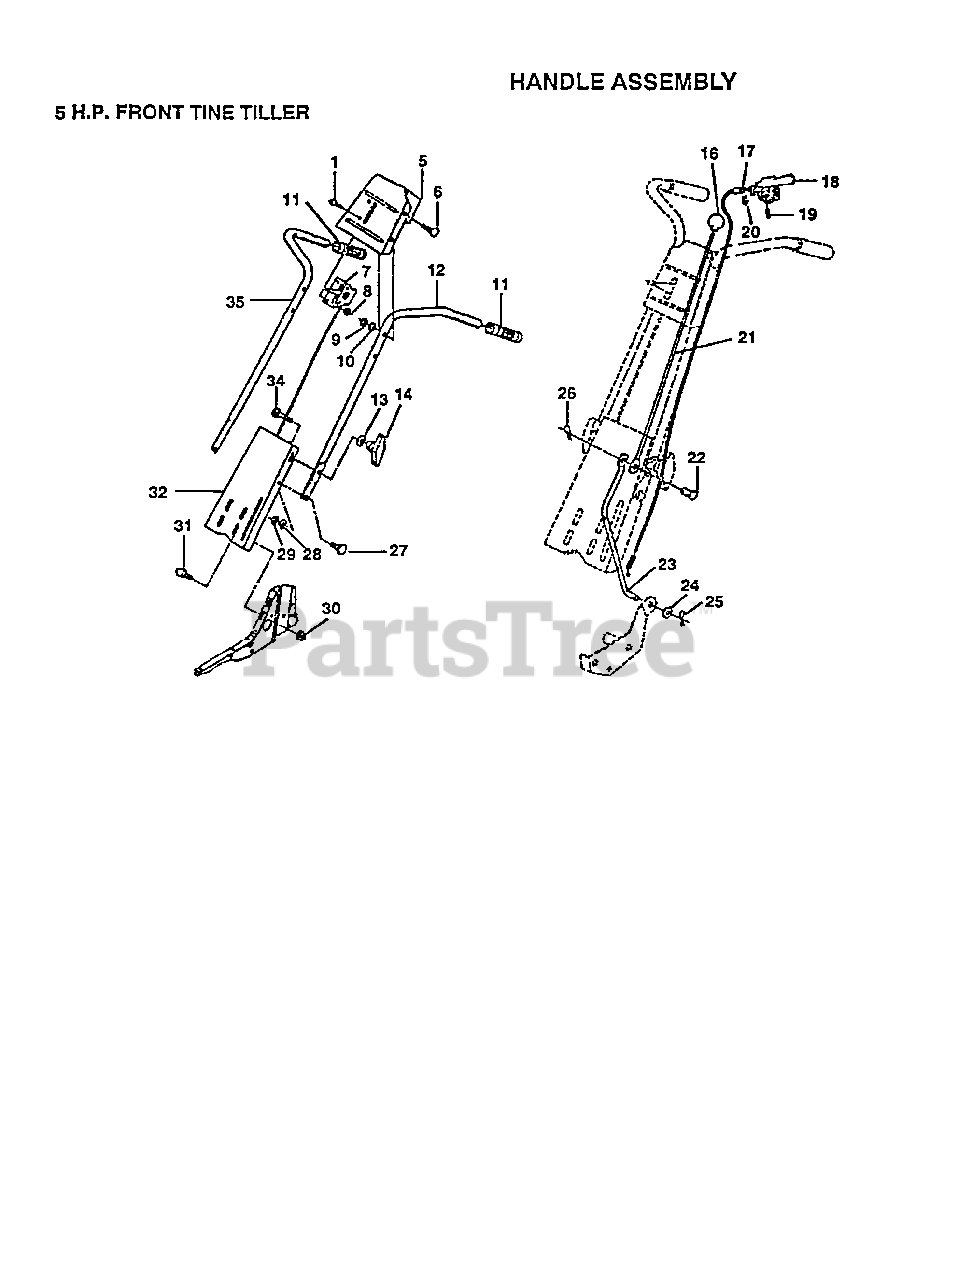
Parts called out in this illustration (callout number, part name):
1	SCREW
6	BOLT
10	WASHER
13	WASHER
17	CABLE CLUTCH T
18	CONTROL LEVER TI
19	SCREW
20	E-RING
21	ROD REVERSE TI
22	RIVET.RD.HD.DRILL
23	REVERSE ROD TI
24	WASHER
25	COTTER PIN
28	LOCKWASHER
29	NUT.HEX.5/16-18
30	NUT
32	HANDLE PANEL TI
34	BOLT
